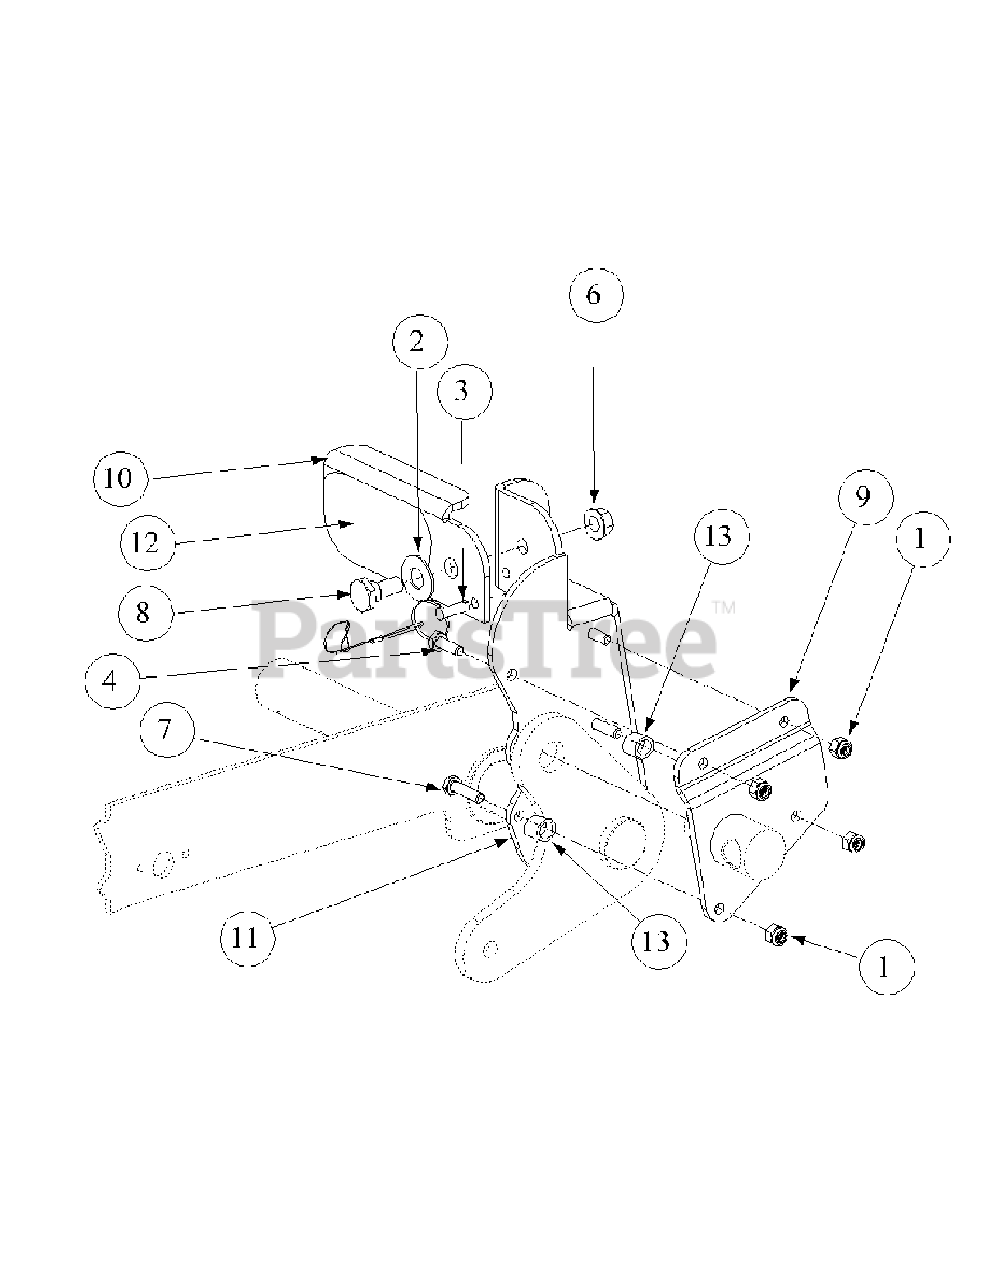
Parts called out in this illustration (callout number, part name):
1	Lock Nut, Nylon Insert, 1/4-20
2	Washer, 1/2 x 1 Shim
3	Detent Pin w/12" Lanyard
4	Hex Cap Screw, 1/4-20, .75
6	Hex Nut, Flange Lock 3/8-16
7	Hex Cap Screw, 1/4-20, 1.00
8	Shoulder Screw, .50 x .27 Lg., 3/8-16
9	Foot Lift Backup Pedal
10	Deck Lift Foot Pedal
11	Deck Lift Foot Pedal
12	Deck Lift Foot Pad
13	Turnbuckle Sleeve
